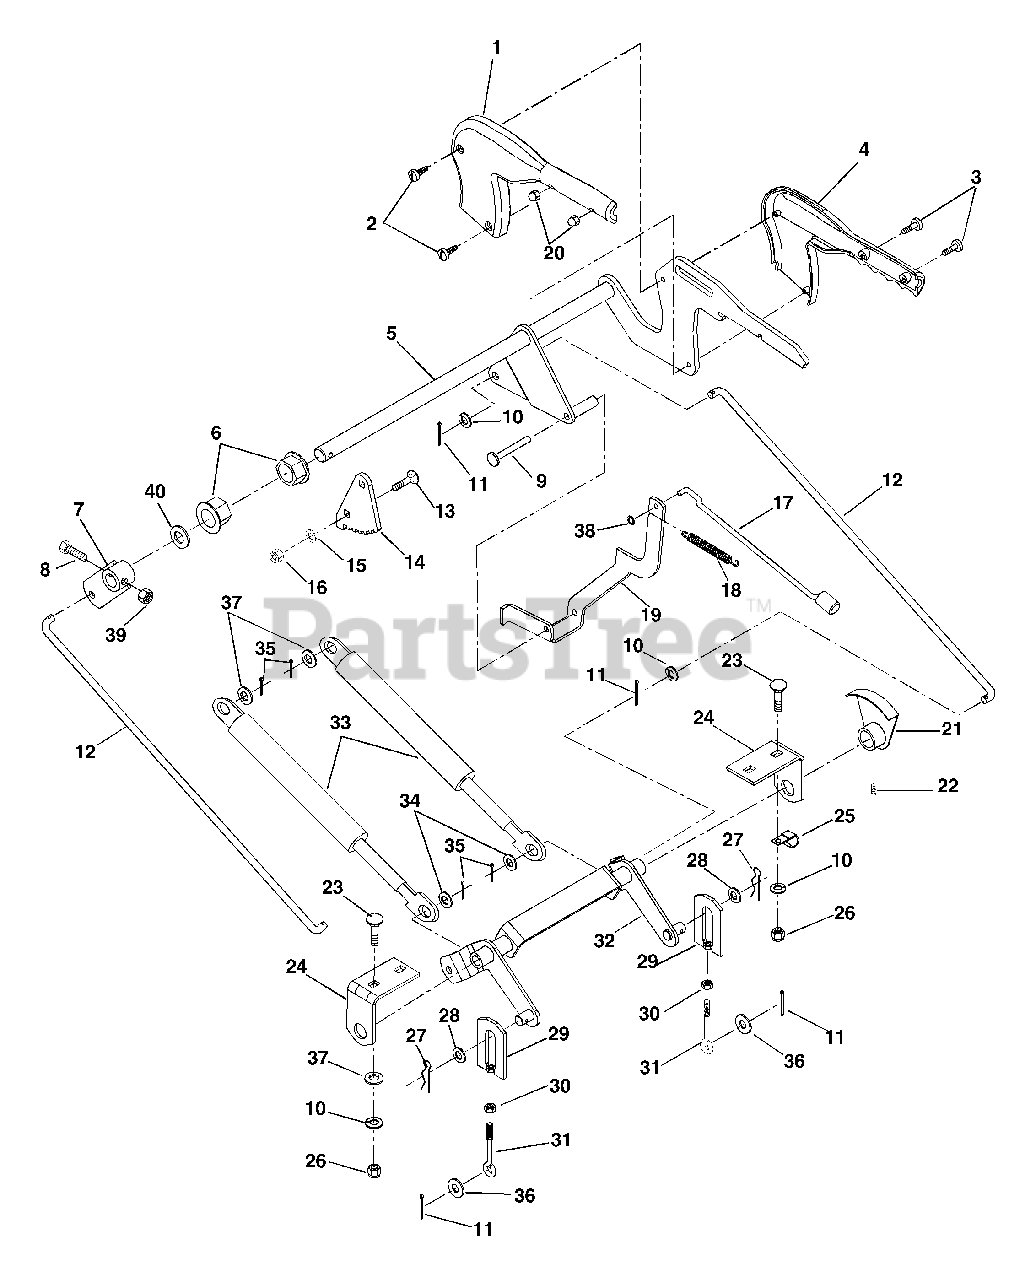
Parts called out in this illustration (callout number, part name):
1	COVER - LIFT RH
2	SCR-TAP 10-16X1.125HI-LOTPHBL
3	SCR-MCH 10-24X.62 P/HD
4	COVER - LIFT LH
5	LEVER, LIFT
6	BSHG-FLG .750X.873HEXX.53X1.18
7	ARM, LIFT
8	BLT-HEX .25-20X1.50 GR8 YWZC
9	PIN, PIVOT .312 X 2.56
10	@WSHR-LK .38X.094 REG YWZC
11	@PIN-CTR .12X1.00 EXTPRSQCT YZ
12	LINK, LIFT
13	@BLT-RDHDSQNK .31-18X.75 G5YZ
14	QUADRANT, LIFT
15	WSHR-FL-STL .323X.625X.062 YWZ
16	@NUT-LK-CTR .31-18 YWZC
17	PIN, LIFT
18	SG-TENS .048X.44X2.25 WLD 9
19	LEVER, DETENT
20	NUT,10-24 LOW CROWN, ACORN
21	INDICATOR, DECK HEIGHT
22	SCR-SET .25-20X.25 SKHCUP OH
23	BLT-RHHDSQSHNK .38-16X.75 G2YZ
24	BRACKET, CENTER LIFT
25	J-CLAMP
26	@NUT-HEX .38-16 YWZC
27	PIN-HAIR-EXT .12X.31X2.37 YWZC
28	@WSHR-FL-STL.531X1.06X.095YWZC
29	LINK, ADJUSTMENT
30	NUT-HEX-JAM .375-16 YWZC
31	BLT-EYE .375-16X2.50 YWZC
32	LEVER, CENTER LIFT
33	SG-GAS COMP .315X.75X10.00 120
34	@WSHR-FL-STL.38X.875X.083 YWZC
35	@PIN-CTR .12X.75 EXTPRSQCT YWZ
36	@WSHR-FL-STL.656X1.31X.095 YWZ
37	@WSHR-FL-STL.406X.812X.065 YWZ
38	RG-RTNG-EXT .250X.010
39	@NUT-LK-CTR .25-20 YWZC
40	WSHR-FL-STL .755X1.375X.125
